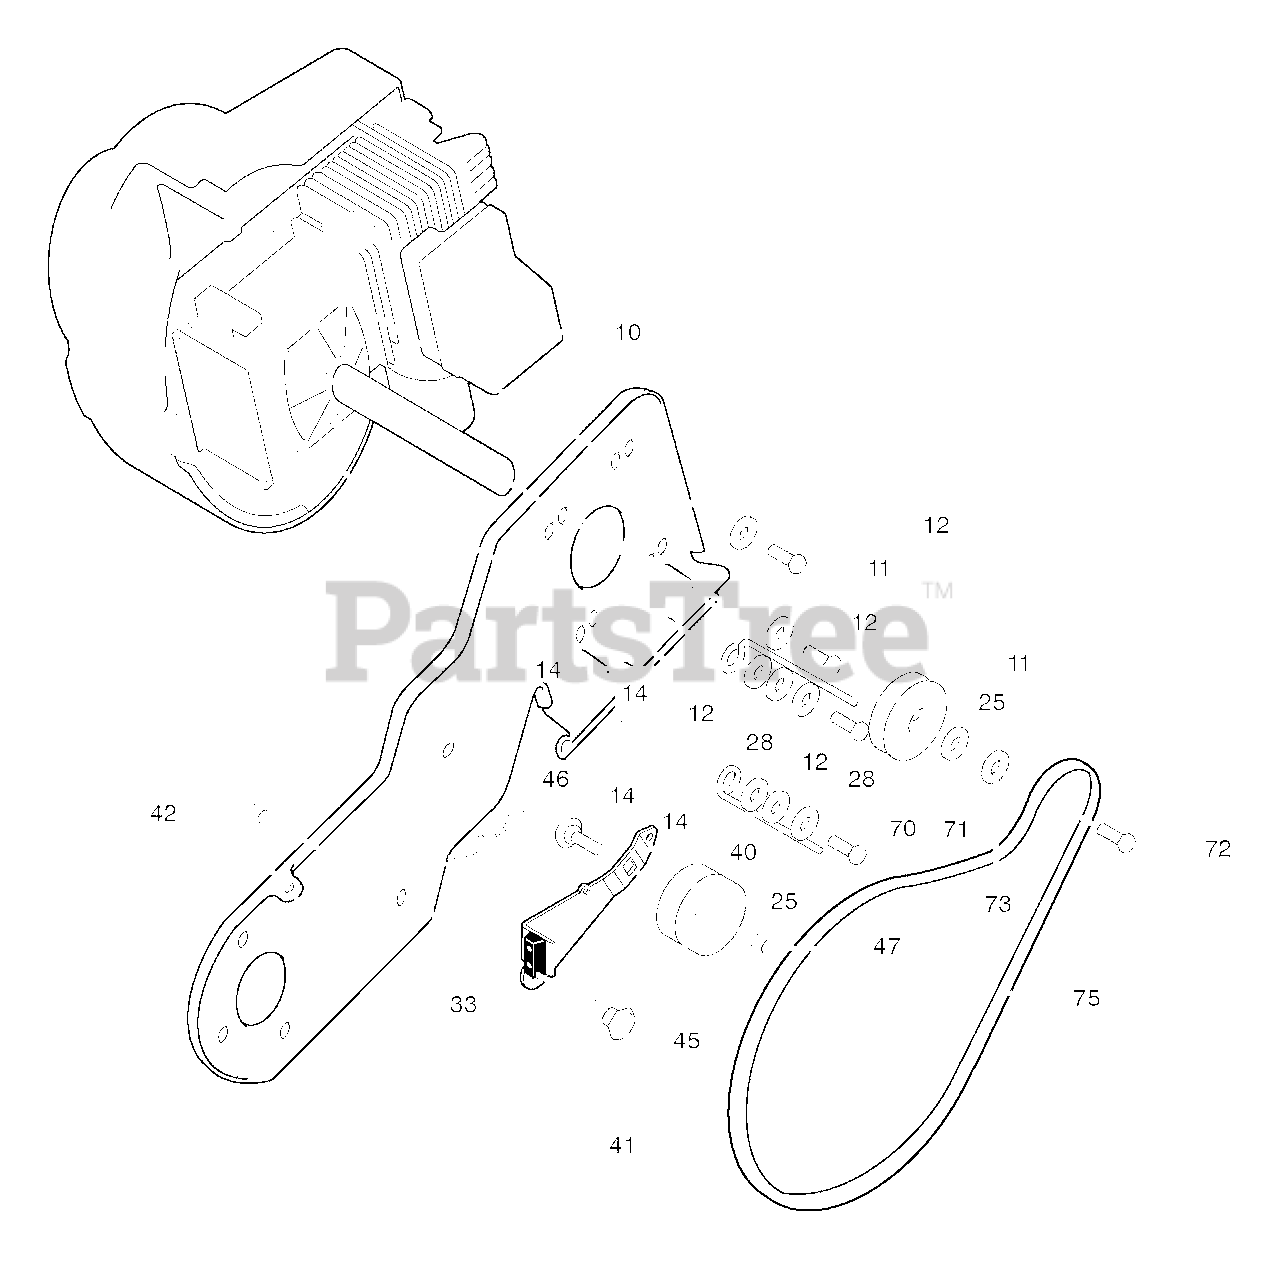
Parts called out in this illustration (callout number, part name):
10	ENGINE
11	SCREW, 5/16-18 x 0.75
12	WASHER
14	WASHER, FLAT
25	GUIDE, BELT
33	SPRING, IDLER BRAKE
40	ASSY, IDLER BRAKE ARM
42	NUT, 5/16-18
45	PULLEY, IDLER
46	BOLT, CARRIAGE
47	NUT
70	PULLEY, ENGINE
71	WASHER, BELLEVILLE
72	SCREW, 5/16-24 x .75
73	WASHER, SPLTLK
75	BELT V 3L 34.8"
